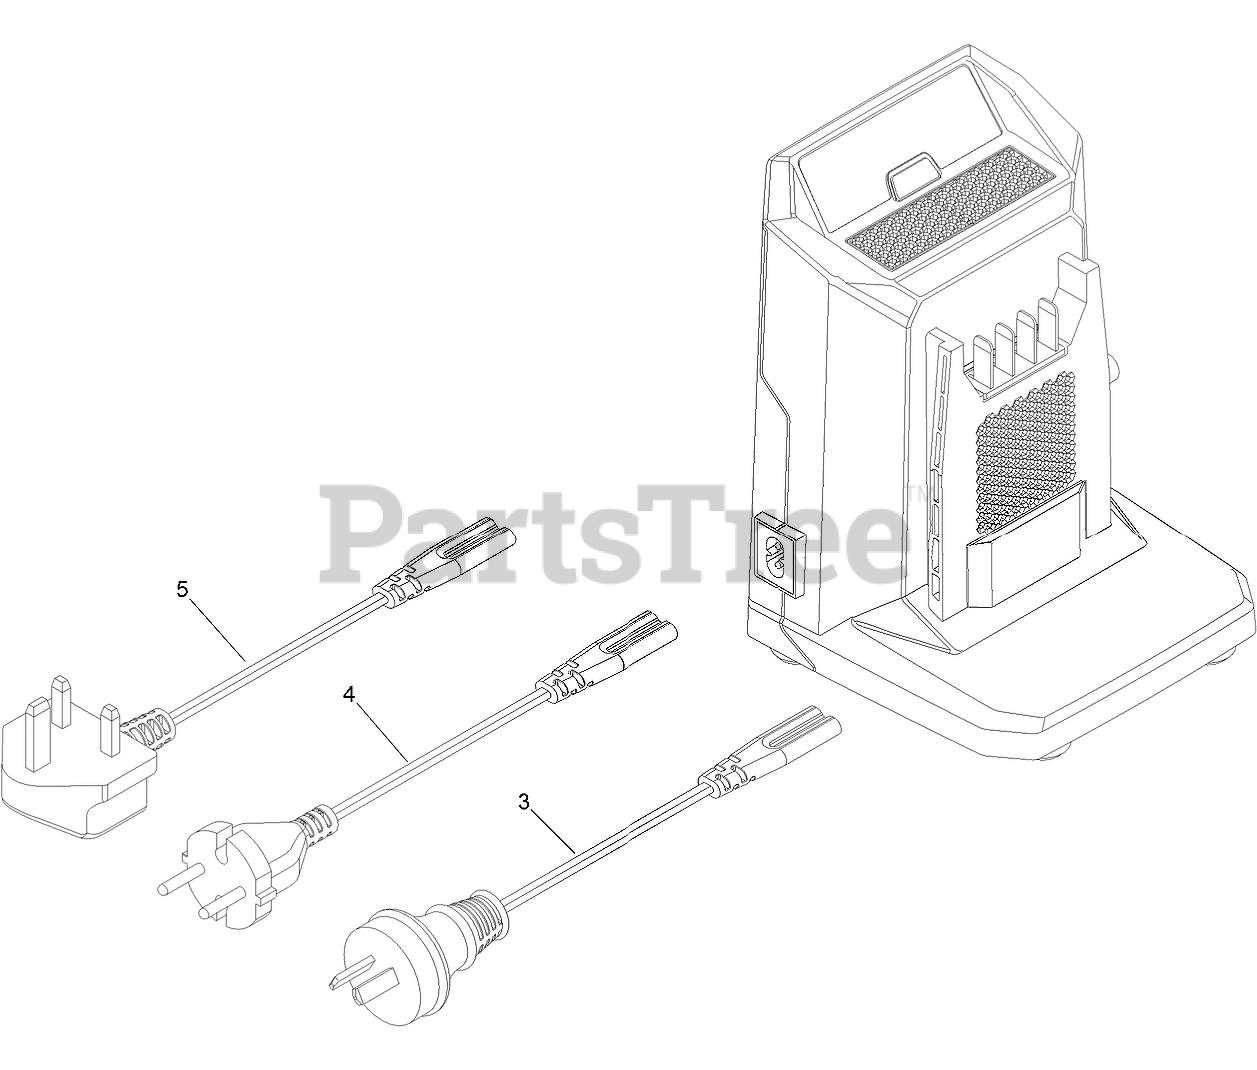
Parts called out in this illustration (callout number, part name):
3	CORD-CHARGER, AU/NZ
4	CORD-CHARGER, CE
5	CORD-CHARGER, UK
